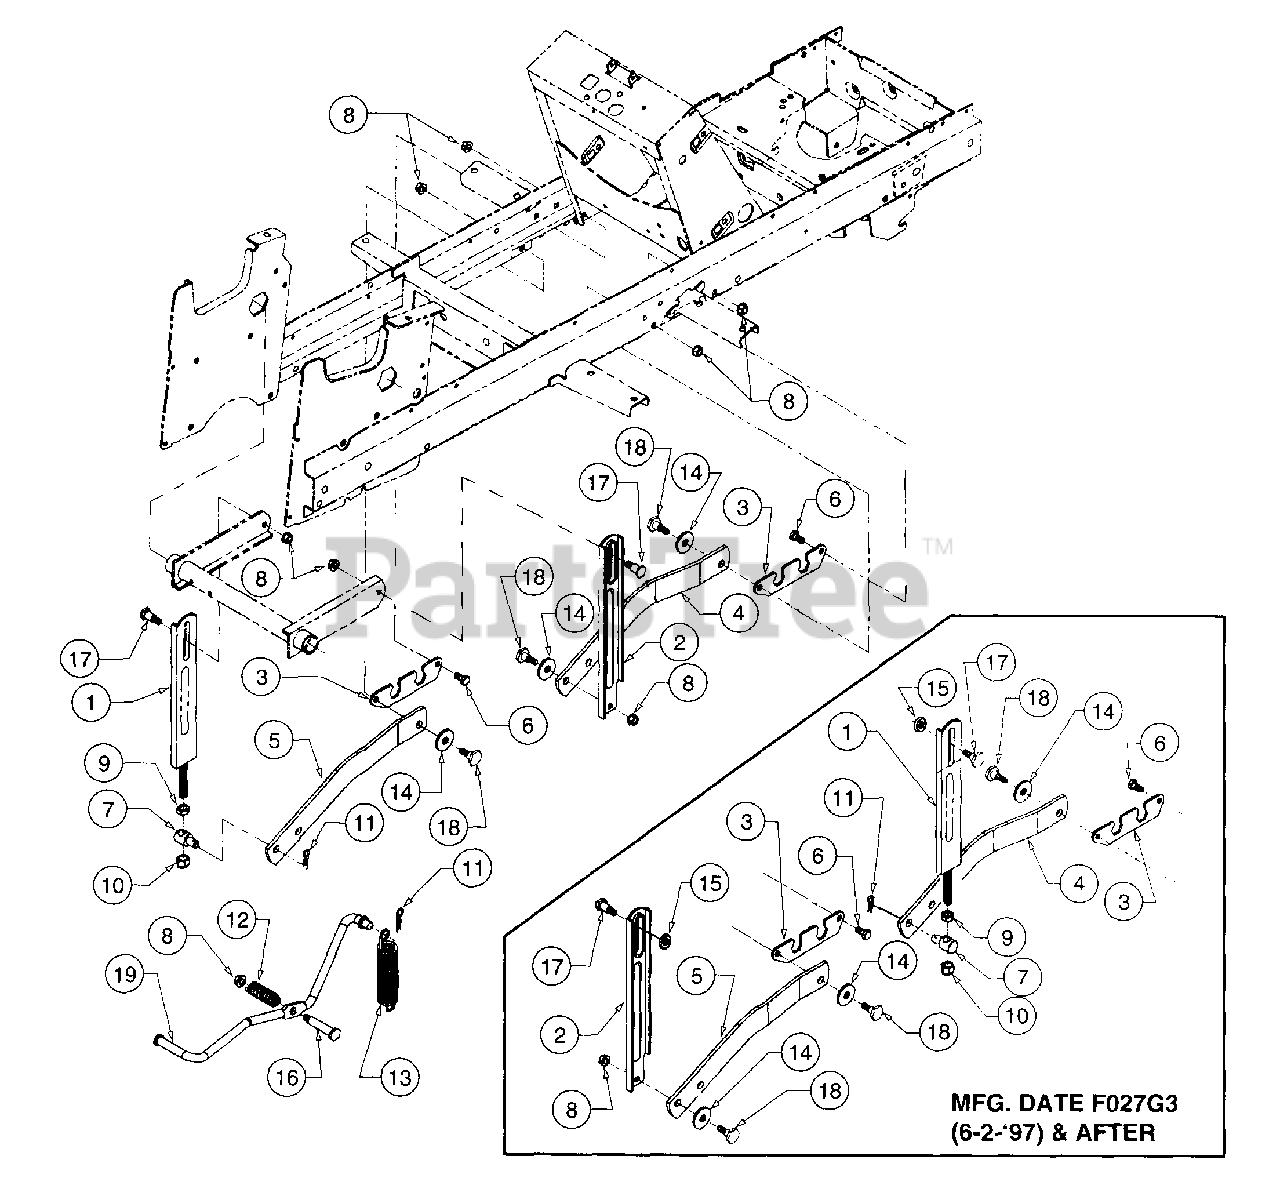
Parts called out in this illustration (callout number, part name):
7	Ferrule, Adjustment
8	Nut,Hex Flange Lock,3/-16
9	Nut,Hex Jam, 1/2 - 13 GR5
10	Nut,Hex Insert Lock, 1/2 - 13
11	Pin,Internal Cotter
12	Spring, Compression, .63 ID x 2.0
13	Spring, Extension, 1.0 OD x 6.42 Lg, 43 Coils, Light Duty 46" Deck
14	Washer, Flat,.50 x 1.5 x .15 Mfg.
15	Washer, Flat,.531 x .875 x .15 Mfg.
16	Bolt, Shoulder
17	Bolt, Shoulder
18	Bolt, Shoulder
19	Rod, RH Lift Assist
